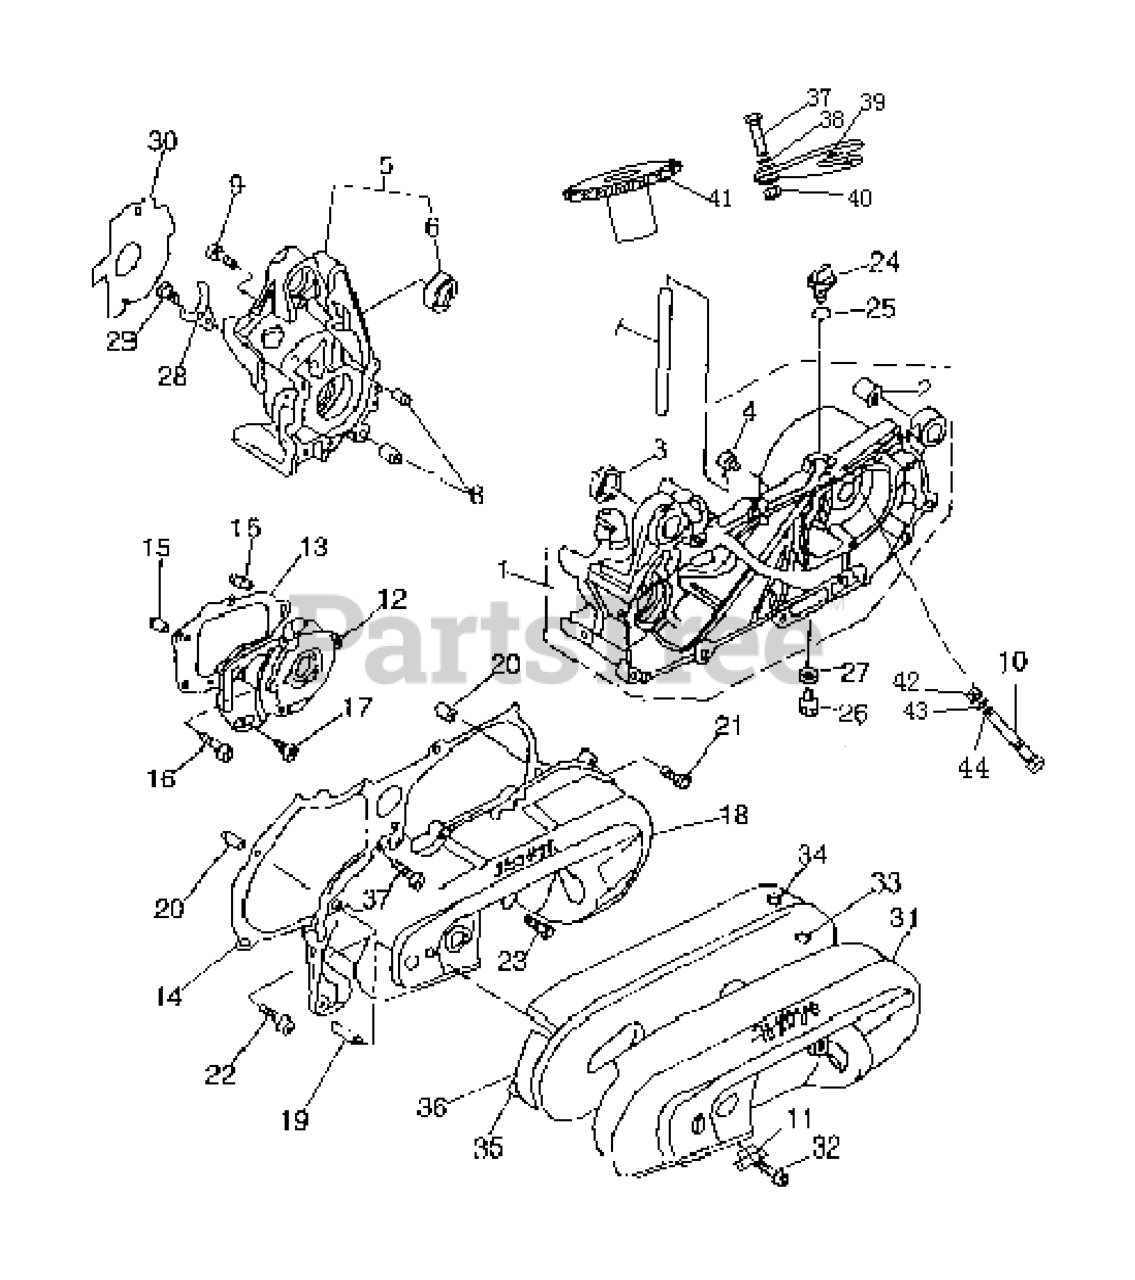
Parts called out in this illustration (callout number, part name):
1	CRANKCASE, LH & RH
2	GROMMET
3	GROMMET
4	BREATHER PLUG
6	GROMMET
8	DOWEL PIN
11	NUT BUSH, RUBBER
12	CRANKCASE COVER
13	GASKET, GEAR BOX
14	GASKET SIDE COVER
15	DOWEL PIN
16	SCREW M6 30
17	SCREW M6 22
18	SIDE COVER
20	DOWEL PIN
21	SCREW M6 25
22	SCREW M6 35
23	SCREW M6 65
24	OIL PLUG
26	FLANGE BOLT
29	SCREW M6 12
31	PROTECTING COVER
39	BRACKET ASSY
41	CHAIN WHEEL ASSY. (17T)
